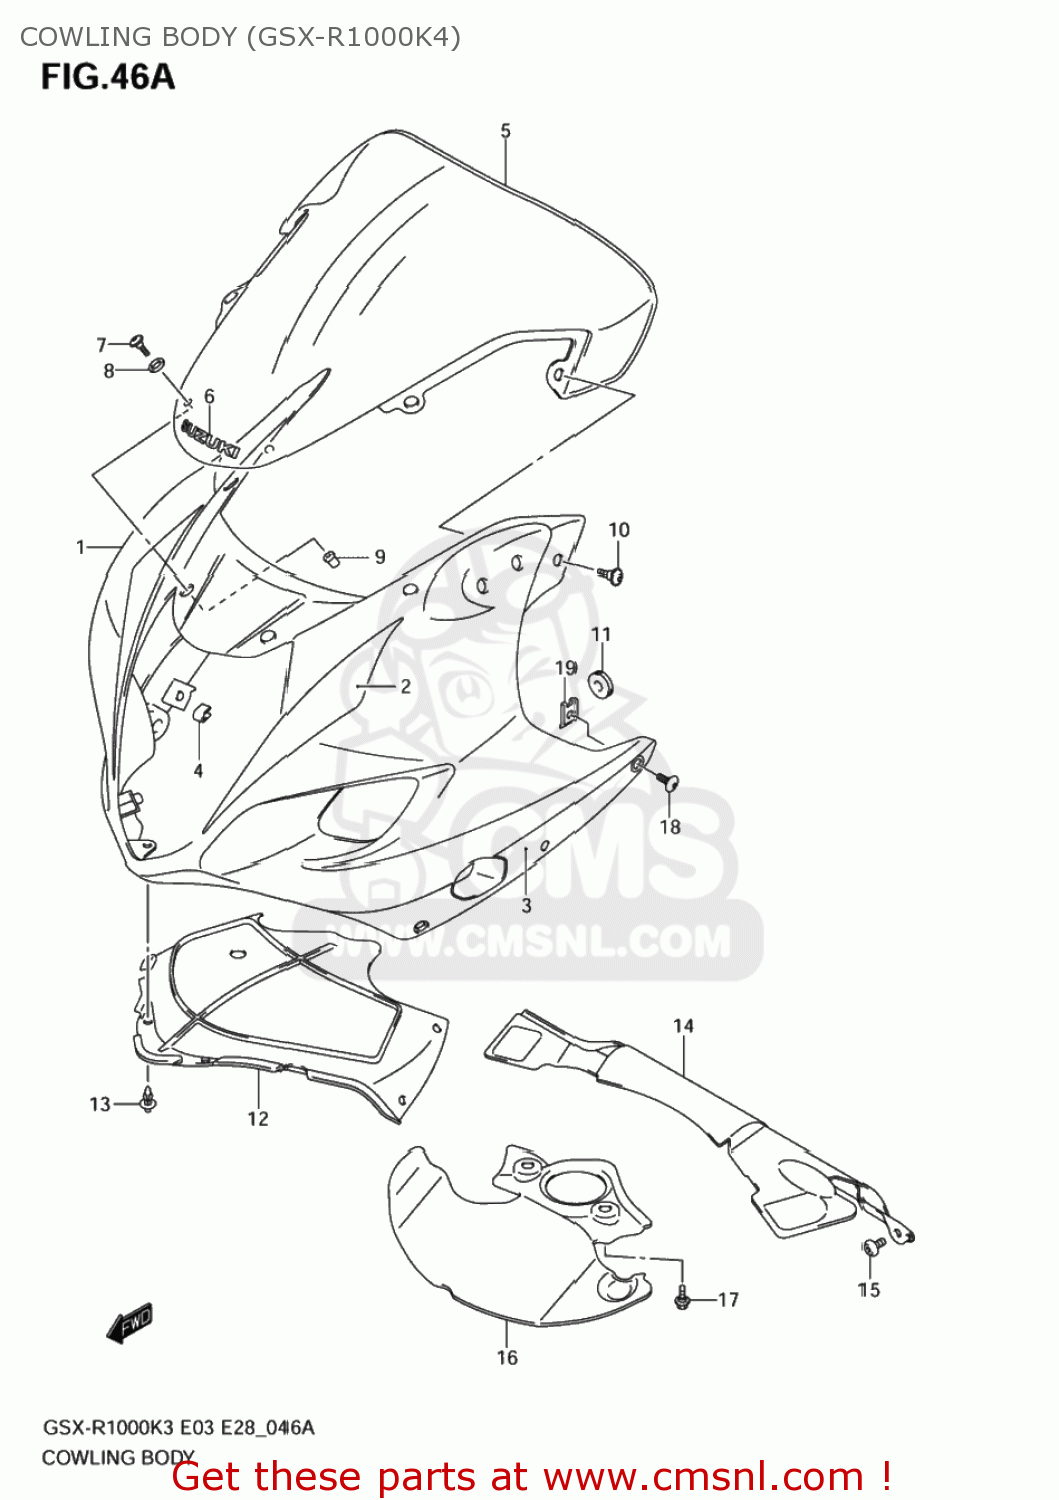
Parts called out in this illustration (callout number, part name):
1	COWLING,BODY(BLUE)
2	TAPE SET,COWL BODY FR
3	TAPE SET,COWL BODY SIDE
4	CUSHION,FR LEG COVER
5	WINDSCREEN
6	TAPE,WINDSCREEN
7	SCREW(5X14)
8	WASHER
9	NUT
10	SCREW(5X16)
11	CUSHION
12	COVER,BODY COWLING
13	CLIP(BLACK)
14	COVER,COWLING FR LWR
15	BOLT(5X13)
16	COVER,LWR BRACKET
17	BOLT
18	SCREW(5X13)
19	NUT,COWL
